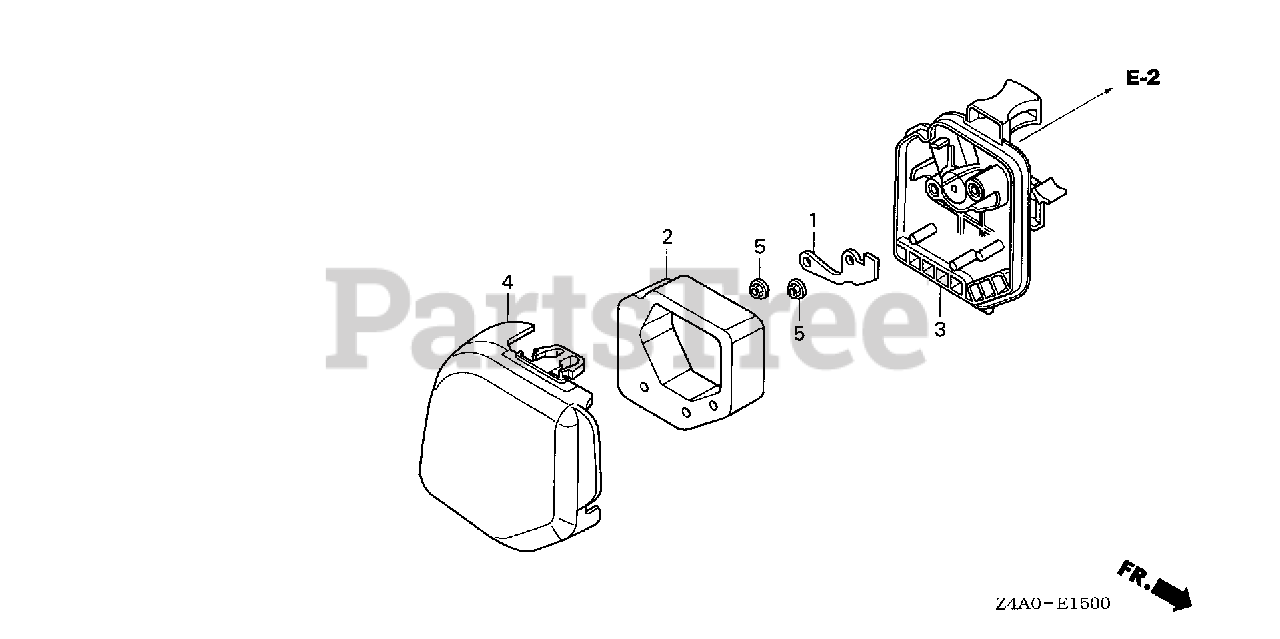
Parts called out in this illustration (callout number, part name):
1	PLATE, OIL TRAP
2	ELEMENT, AIR CLEANER
3	HOUSING, AIR CLEANER
4	COVER, AIR CLEANER
5	NUT, FLANGE (5MM)
